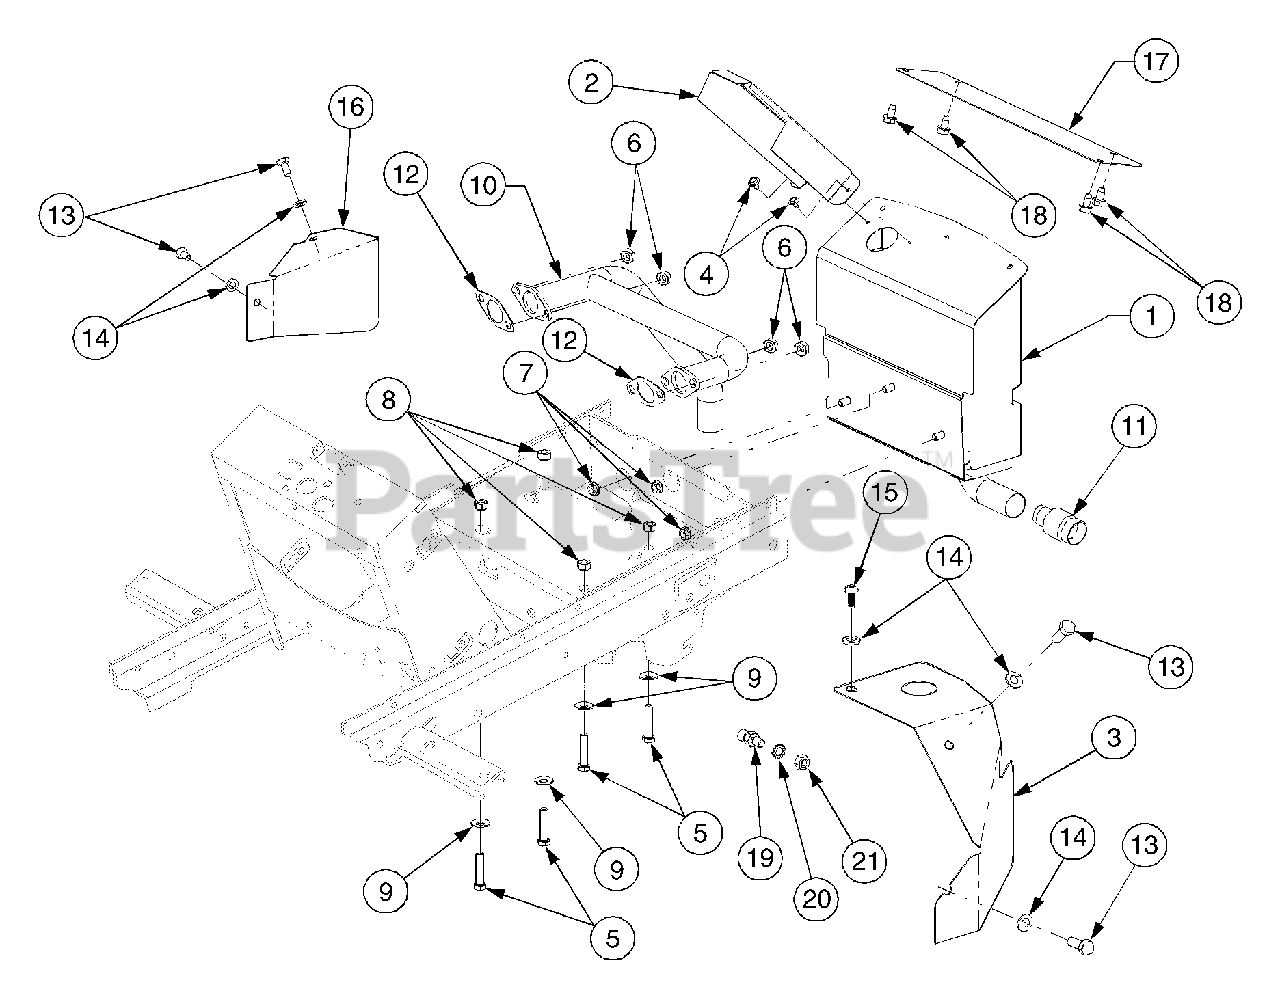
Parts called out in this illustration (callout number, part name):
1	Muffler Assembly
2	Shield, Muffler Tube
5	Bolt, Eng Mount, 3/8-24 x 1.75 GR5
6	Nut, Hex Flange
7	Nut, Hex Flange Lock, 5/16-18
8	Nut, Hex Lock, 3/8-24
9	Washer, Bell, .380 x .88 x .062
10	Tube, Exhaust
11	Arrestor, Spark
12	Gasket, Exhaust
13	Screw, Hex Cap, M6 x 1 x 10
14	Washer, Flat, .281 x .5 x .06
15	Screw, Truss Hd Tapp, #10 x .5
18	Screw, Hex Wsh Hd Tap, 1/4-20 x .5
19	Stud, Gound
20	Nut, Hex, 5/16 - 18 GR5
21	Wash, Ext. Tooth Lock, 5/16
